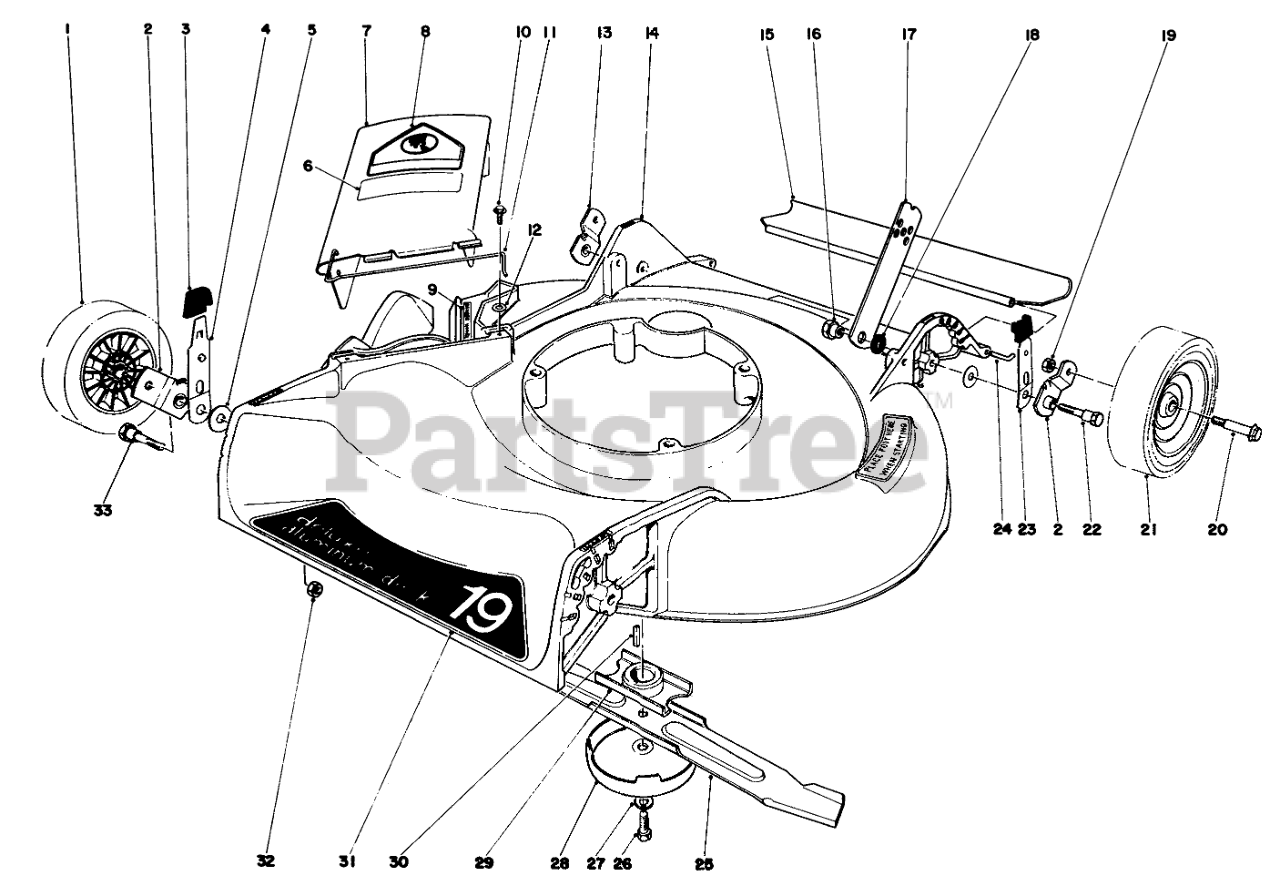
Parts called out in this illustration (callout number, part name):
1	Wheel & Tire Assembly
2	Pivot Arm
3	KNOB-ARM
4	SPRING ARM ASM
5	WASHER-PIVOT
6	DECAL DEFLECTOR
7	Deflector-Cover Assembly (Incl. Ref. #6, 8 & 11)
8	DECAL-DANGER
9	Decal
10	SCREW
11	SPRING HINGE
12	WASHER-FLAT
13	Pivot Arm
14	Housing (Incl. Ref. #9)
15	Rear Shield
16	HANDLE PIVOT NUT
17	Handle Latch
18	HANDLE LATCH SPACER
19	Nut
21	Wheel & Tire Assembly
22	PIVOT SCREW
23	SPRING ARM ASM
24	SHIELD ROD
25	Blade
26	SPECIAL SCREW
27	WASHER-LOCK
28	AntiScalp Cup
29	Blade Retailer
30	KEY-SQUARE
31	Decal
32	Nut
33	PIVOT SCREW
